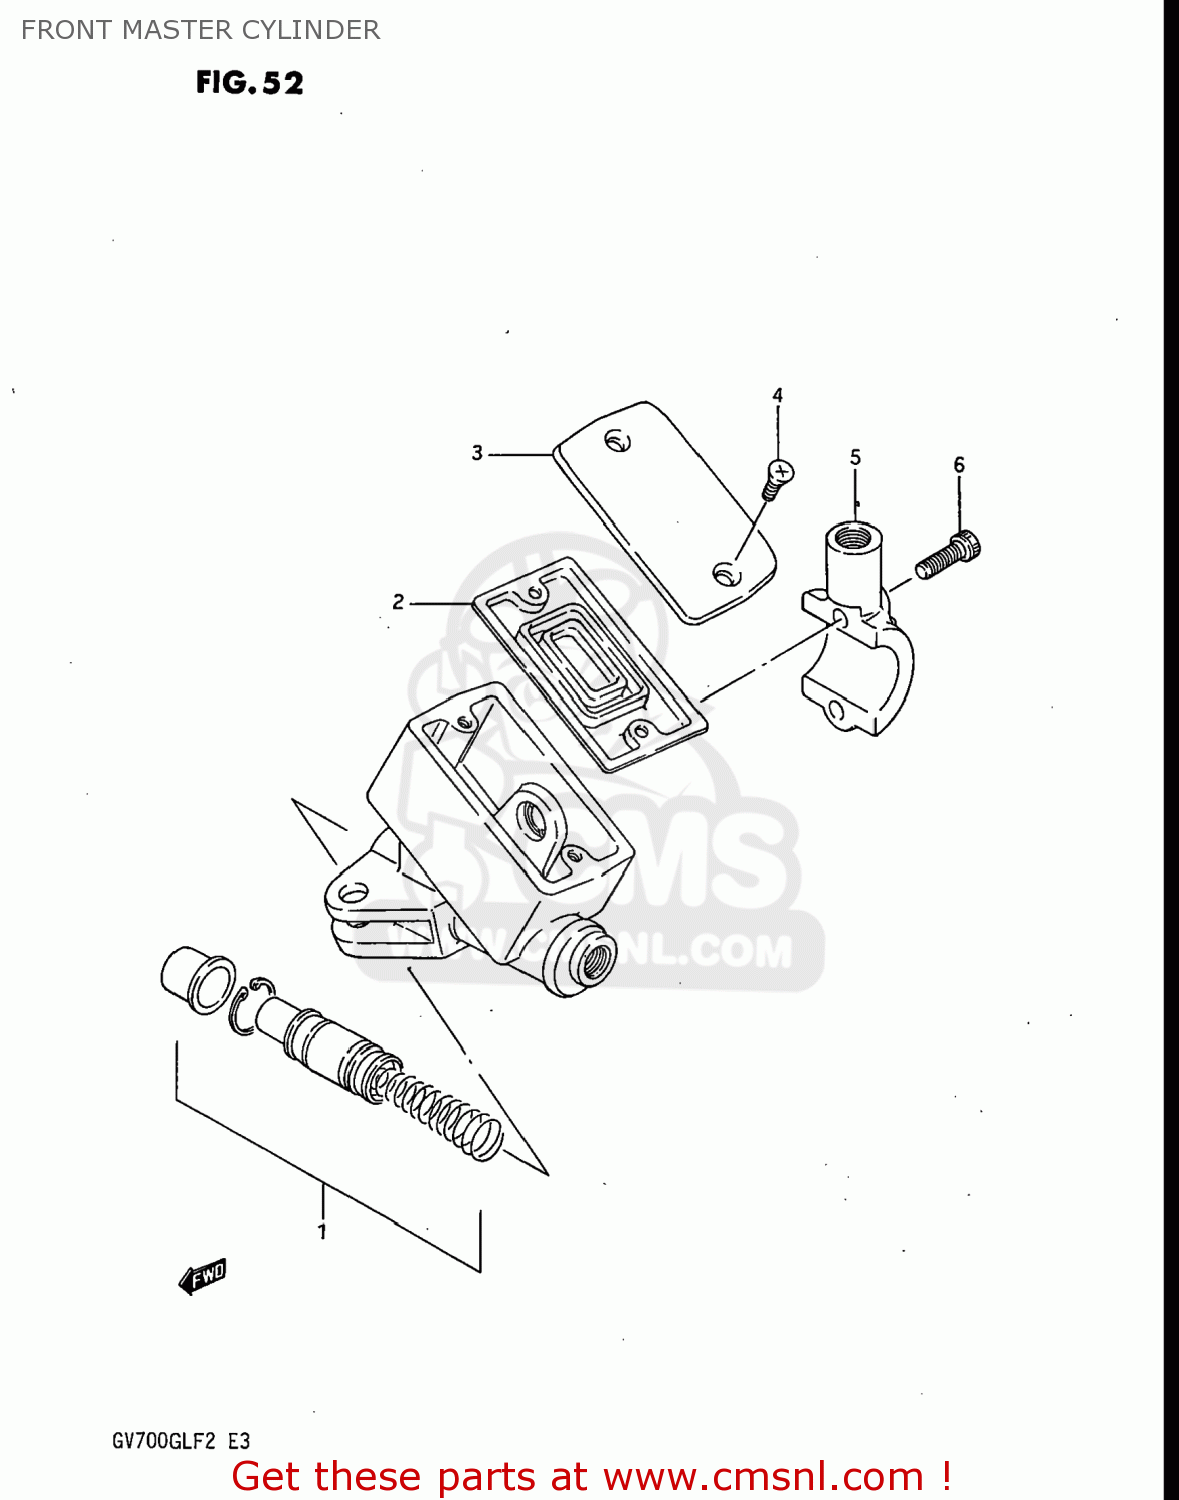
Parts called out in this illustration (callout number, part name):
1	PISTON & CUP SET
2	3
3	CAP
4	SCREW
5	HOLDER
6	BOLT
